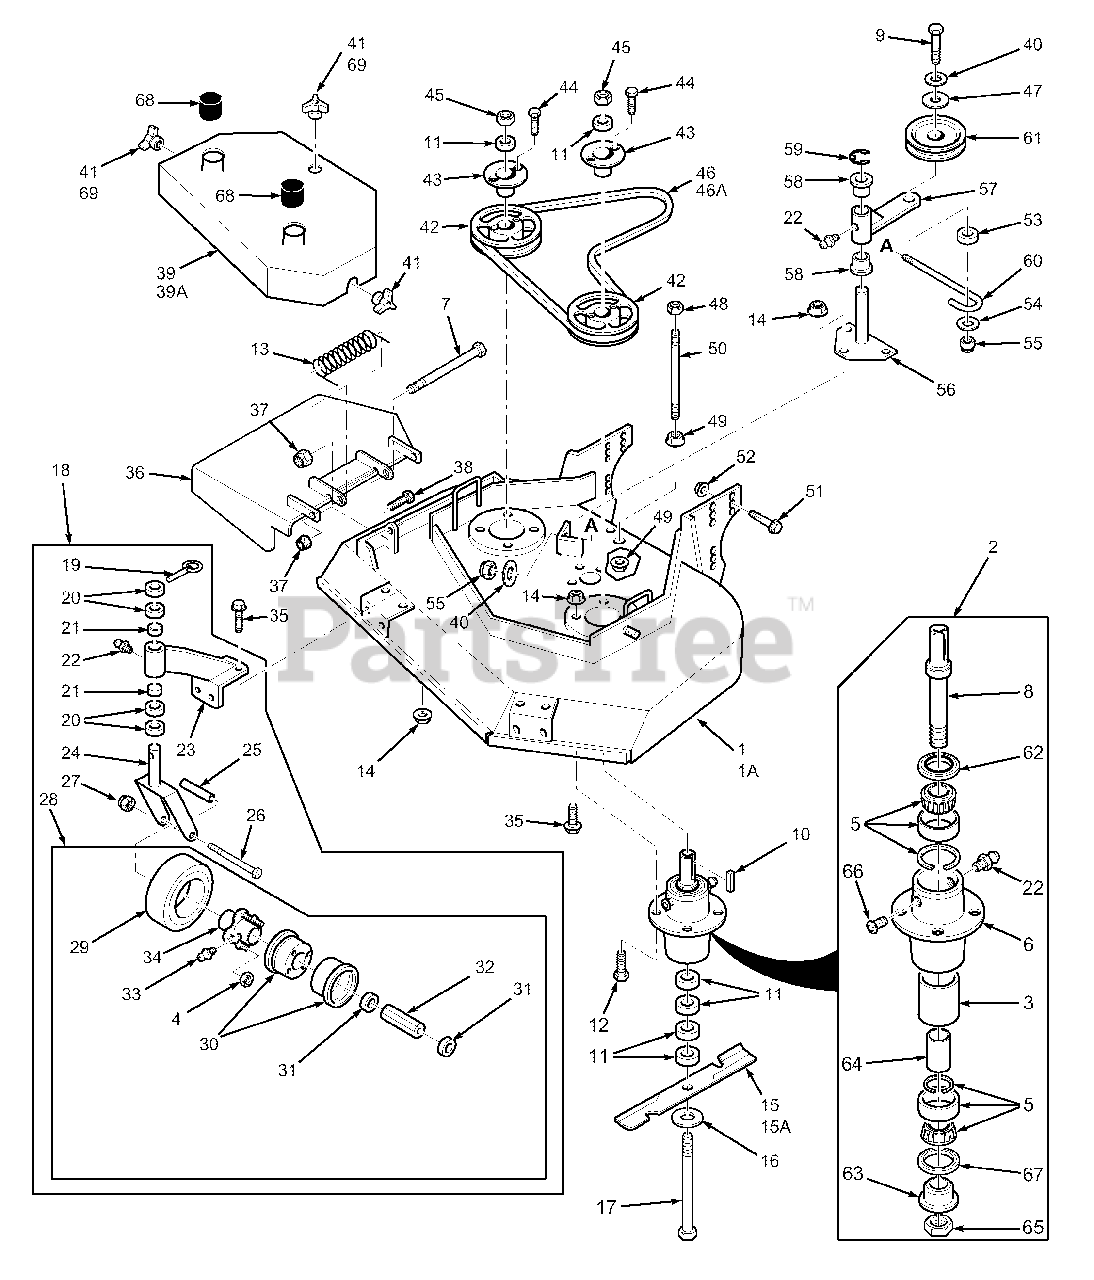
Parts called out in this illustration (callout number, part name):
1	Cutter Deck
1A	Cutter Deck
2	Cutter Spindle Assy.
3	Spacer, Outside
4	Tapered Nut, 5/16-24
5	Tapered Bearing (Two)
6	Spindle Housing
7	Bolt, 5/16-18 x 4-1/4" Hex Head
8	Spindle Shaft
9	Bolt, 3/8-16 x 3-1/2" Hex Head
10	Key, 1/4 x 1/4 x 2"
11	Spacer, Cutter Blade - Small
12	Bolt,5/16-18 x 1-1/4" Hex Head
13	Spring, Chutte Return
14	Nut 5/16-18 Serrated Flange
15	Cutter Blade, 18"
15A	Cutter Blade, 18 Hi Lift
16	Flatwasher, 5/8 W
17	Hex Hd. Bolt, 5/8-11 x 9-1/2"
18	Caster Assembly
19	Quick Pin
20	Spacer, Caster Yoke, 1/2" long
21	Bronze Bearing
22	Grease Fitting
23	Support Assembly
24	Caster Yoke
25	Sleeve, Caster Wheel Bearing
26	Hex Hd. Bolt, 1/2-13 x 5-1/2"
27	Elastic Stop Nut, 1/2-13
28	Wheel Assy.
29	Tire only, Caster Wheel
30	Rim Pair, Caster Wheel
31	Retainer, Bearing, Caster Wheel
32	Roller Bearing, Caster Wheel
33	Grease Fitting, 45 degree 1/4-28
34	Hub Assembly
35	Cpscrw,5/16-18 x 3/4" Ser.Flg. Hex Head
36	Discharge Chute
37	Hex Nut, 5/16-18 Elastic Stop
38	Hex Hd Bolt, 5/16-18 x 1"
39	Belt Cover Assy
39A	Belt Cover Assembly w/decals (SWZ36A-15KA)
40	Flat Washer, 3/8" Special
41	Wing Nut, 3/8-16
42	Pulley
43	Tapered Hub
44	Hex Hd. Bolt, 1/4-20 x 3/4"
45	Hex Nut, 5/8-11
46	Belt, Blade Drive
47	Spacer
48	Hex Nut, 3/8-16 Center Locknut
49	Nut, 3/8-16 Serrated Flange
50	Support, Belt Cover
51	Cpscrw, 7/16-14 x 1" Ser. Flg. HH
52	Nut, 7/16-14 Serrated Flange
53	Spacer, J-Hook
54	Washer, 3/8 x 1-1/2 x 16 GA
55	Elastic Stop Nut, 3/8-16
56	Idler Pivot
57	Idler Arm Assy.
58	Bronze Bearing
59	Retaining Ring, 1-1/8" Ext. "E"
60	J-Hook
61	Idler Pulley, Belt Clutch
62	Seal, Cutter Spindle
63	Spindle Bushing
64	Spacer, Inside
65	Nut, 1-1/16 - 18 Thread
66	Relief Fitting, Cutter Spindle
67	Seal, Cutter Spindle
68	Spindle Shield
69	Wing Nut, 3/8-16 (Small) Top Side
69	Wing Nut, 3/8-16 (Small) RH Side
